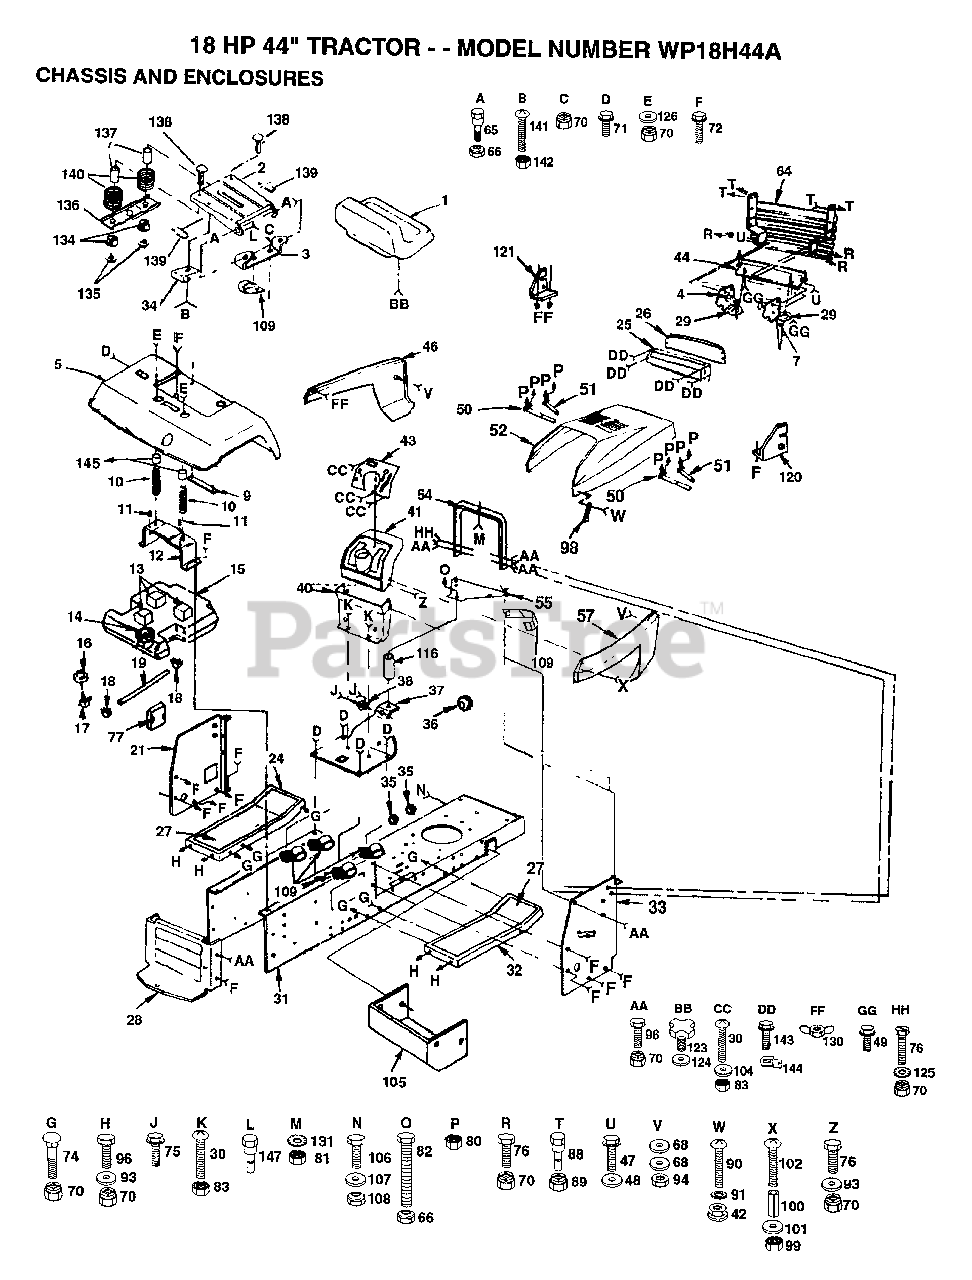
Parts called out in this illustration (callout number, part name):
4	SUPPORT LH YTH
5	FENDER
7	SUPPORT RH YTH
10	SPRING COMPRESSIO
11	NUT-PUSH YT
13	PAD-SPACER LT
16	BUSHING OUTLET T
17	FUEL TANK STEM GT
18	HOSE CLAMP
21	PANEL DASH LH
26	LENS LT
27	FOOTREST PAD
28	DRAWBAR LT/YT
29	WASHER
30	SCREW
33	DASH PANEL RH
36	SNAP BUSHING T
40	LOWER DASH
42	WELDNUT
47	SCREW
48	WASHER
49	SCREW
54	SUPPORT ASS'Y
57	"PANEL,SIDE RH "
68	WASHER PM
71	SCREW LT
72	SCREW
74	BOLT
76	BOLT
77	COVER ACCESS
80	NUT
82	BOLT
90	SCREW
91	LOCKWASHER
93	WASHER
98	HOOD LATCH T
100	SPACER LT
101	WASHER
102	SCREW
104	WASHER
106	BOLT LT
107	WASHER
108	"NUT,SELF RETAININ"
109	CLIP T
116	SPACER
120	SUPPORT RH YTH
121	SUPPORT LH YTH
123	"KNOB 1/2"" YT"
124	WASHER
125	LOCKWASHER
126	WASHER
134	BUSHING
136	BRKT SWITCH
137	SPACER SPLIT
139	STRIP FORM
140	SPRING
142	"NUT,KEPS"
144	"""J"" FASTENER LT"
145	CAP SPRING
147	"BOLT,SHOULDER"
